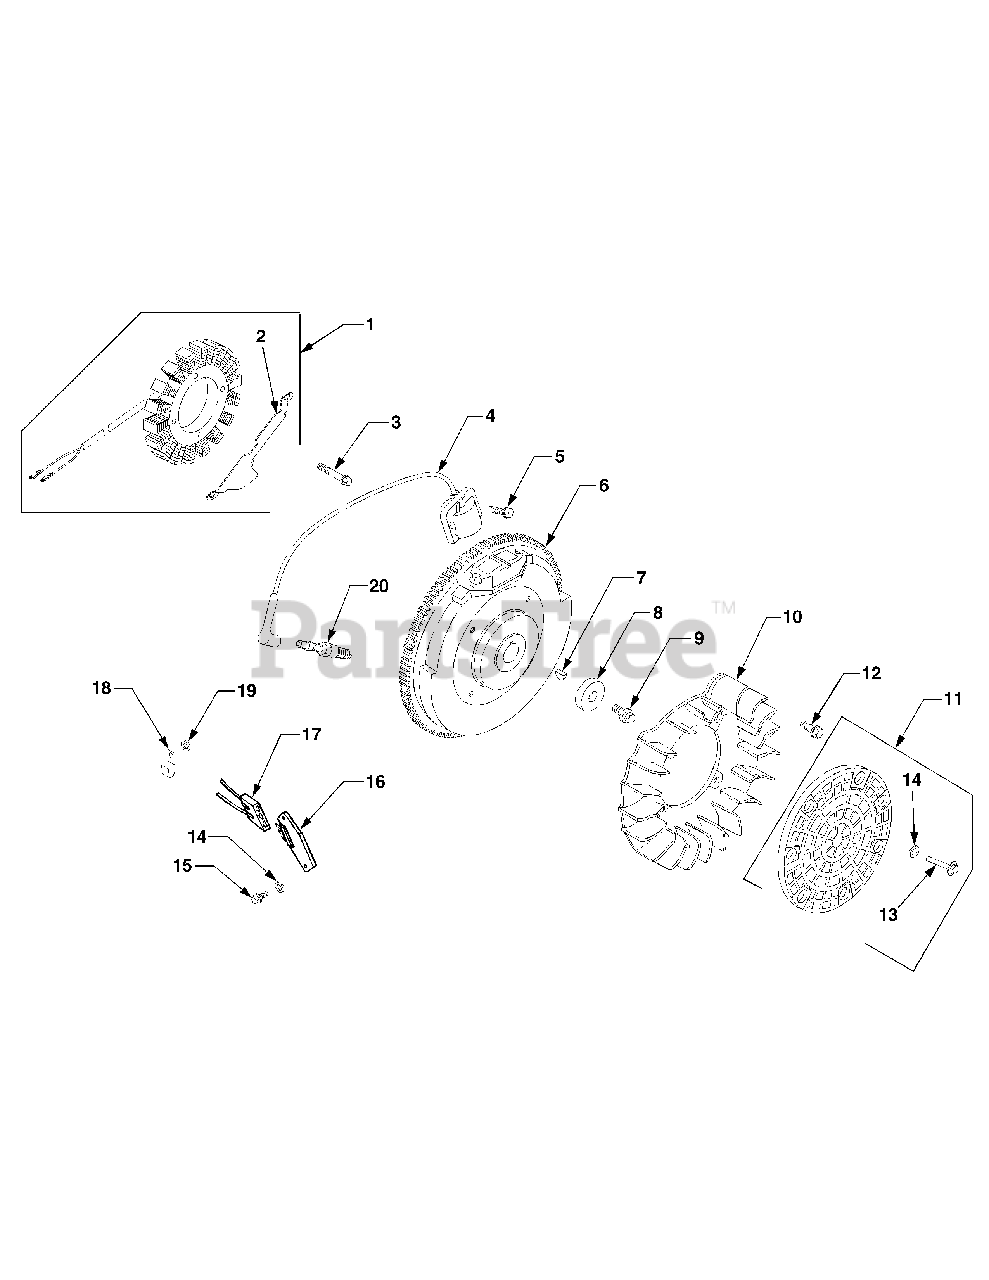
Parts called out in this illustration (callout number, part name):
1	Kit, 15 Amp Stator (Includes Ref. 2)
2	Bracket, Stator
3	Screw, Hex Cap M5 x 0.8 x 25 .
4	Module, Ignition
5	Screw, Hex Flange M5 x 0.8 x 20
6	Flywheel
8	Washer, Plain 3/8"
9	Screw, Hex Flange M10 x 1.5 x 46
10	Fan
11	Kit,Grass Screen (Includes Ref. Nos. 13-15)
12	Bolt, Shoulder, M6 x 1.0 x 16 ...
13	Screw, Hex Cap M4 x 0.7 x 25 .
14	Washer, Plain 3/16"
15	Screw, Phillips Hd. 11-16 x 7/8"
16	Rectifier-regulator 15 Amp
17	Connector (3 Contact)
18	Clip, Cable
19	Washer, Plain 1/4"
20	Spark Plug
